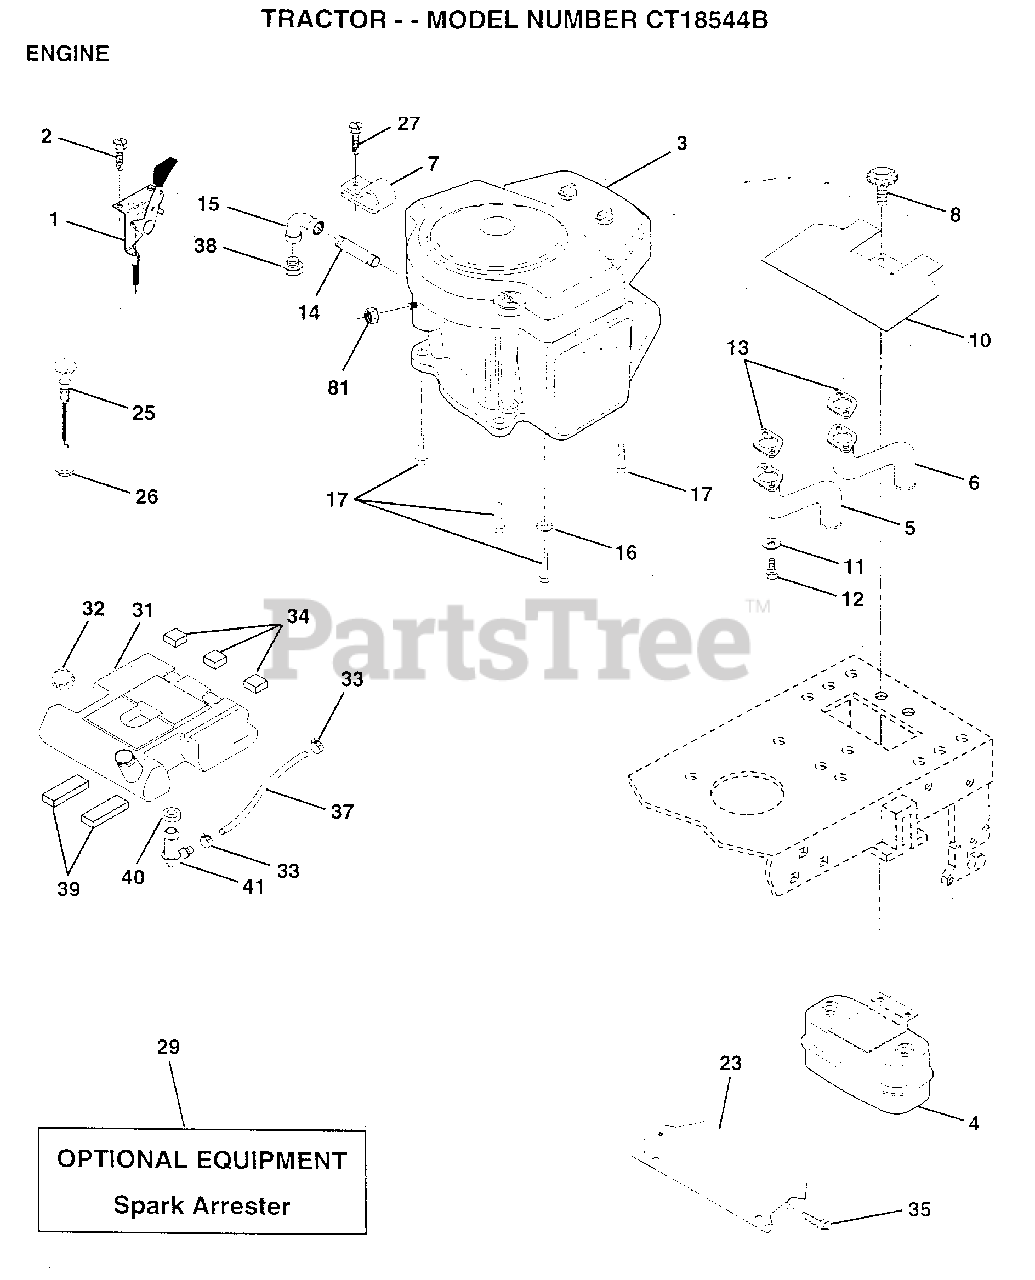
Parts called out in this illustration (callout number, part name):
2	SCREW LT
3	ENGINE, BRIGGS
4	MUFFLER.TW.LOTONE
5	EXHAUST.B&S.18.LH
6	EXHAUST.B&S.18.RH
7	CLAMP.TUBE.DBL.EN
8	BOLT.5/16-18.UNC
10	SHIELD.HEAT.
11	LOCKWASHER
13	GASKET MUFFLER
14	PIPE NIPPLE LT
15	ELBOW
16	LOCKWASHER
17	SCREW LT
25	"CONTROL.CHOKE.51"""
26	"NUT,KEPS 3/8-24IM"
27	"SCREW-TT,10-32 FL"
31	TANK FUEL REAR
32	CAP ASM FUEL
33	HOSE CLAMP
34	PAD-SPACER LT
35	SCREW
37	FUEL LINE T
39	PAD IDLER TI
40	BUSHING OUTLET T
41	STEM.TANK.FUEL
81	NUT
